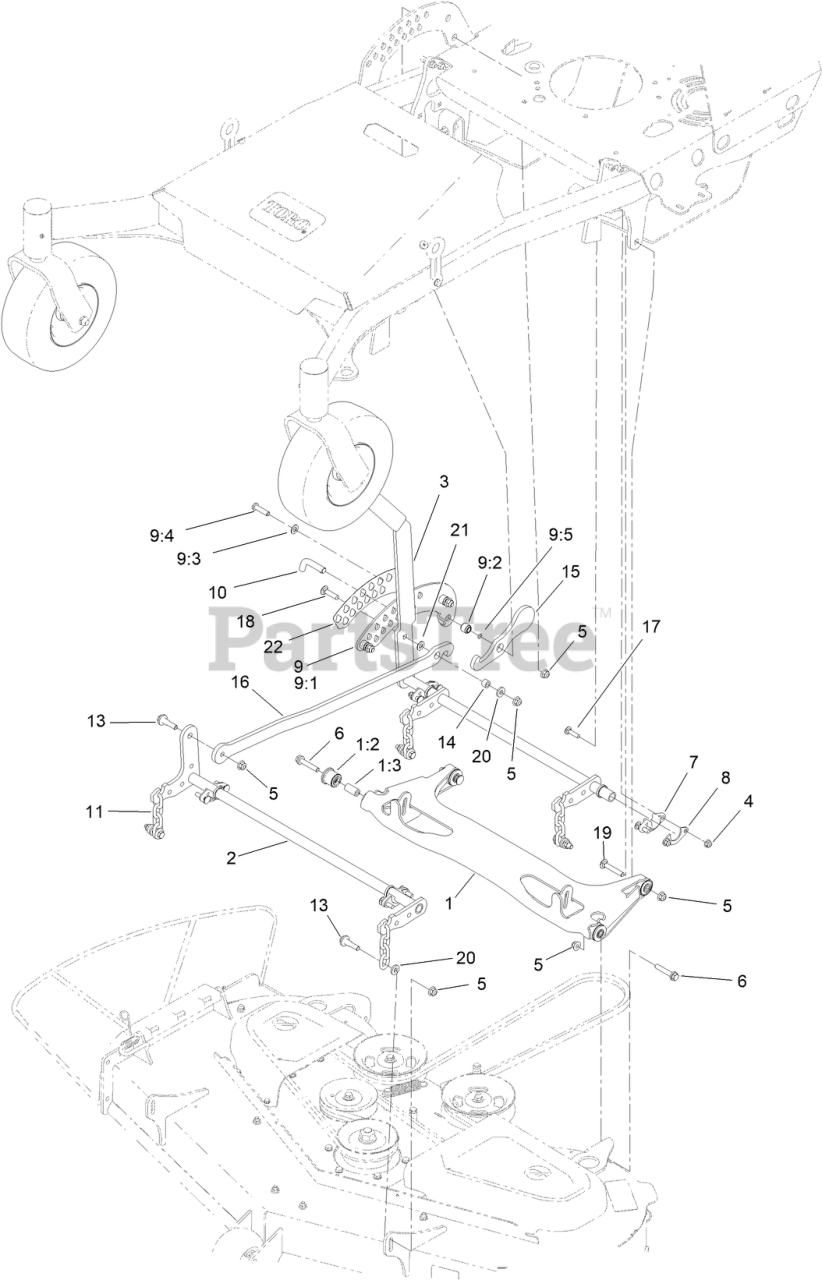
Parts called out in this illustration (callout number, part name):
1	DECK STRUT ASM
1:2	BUSHING-RUBBER, SUSPENSION
1:3	SPACER
2	PIVOT ASM-FRONT
3	PIVOT ASM
4	NUT-HF, NI
5	NUT-HF, NI
6	SCREW-HHF
7	BEARING-FLANGE
8	GUSSET-DECK LIFT
9	HOC STANDOFF ASM
9:1	PLATE - HOC
9:2	SPACER-DOUBLE STEP
9:3	WASHER-PLAIN
9:4	SCREW-HSBH
9:5	O-RING
10	PIN-HOC
11	CHAIN-DECKLIFT, 4-LINK
13	BOLT-SHOULDER
14	SPACER
15	LEVER-LOCK
16	LINK - HOC
17	SCREW-CARR
18	SCREW-CARR
19	SCREW-CARR
20	SPACER-HUB, BLOWER
21	WASHER-PLAIN
22	DECAL-HOC
